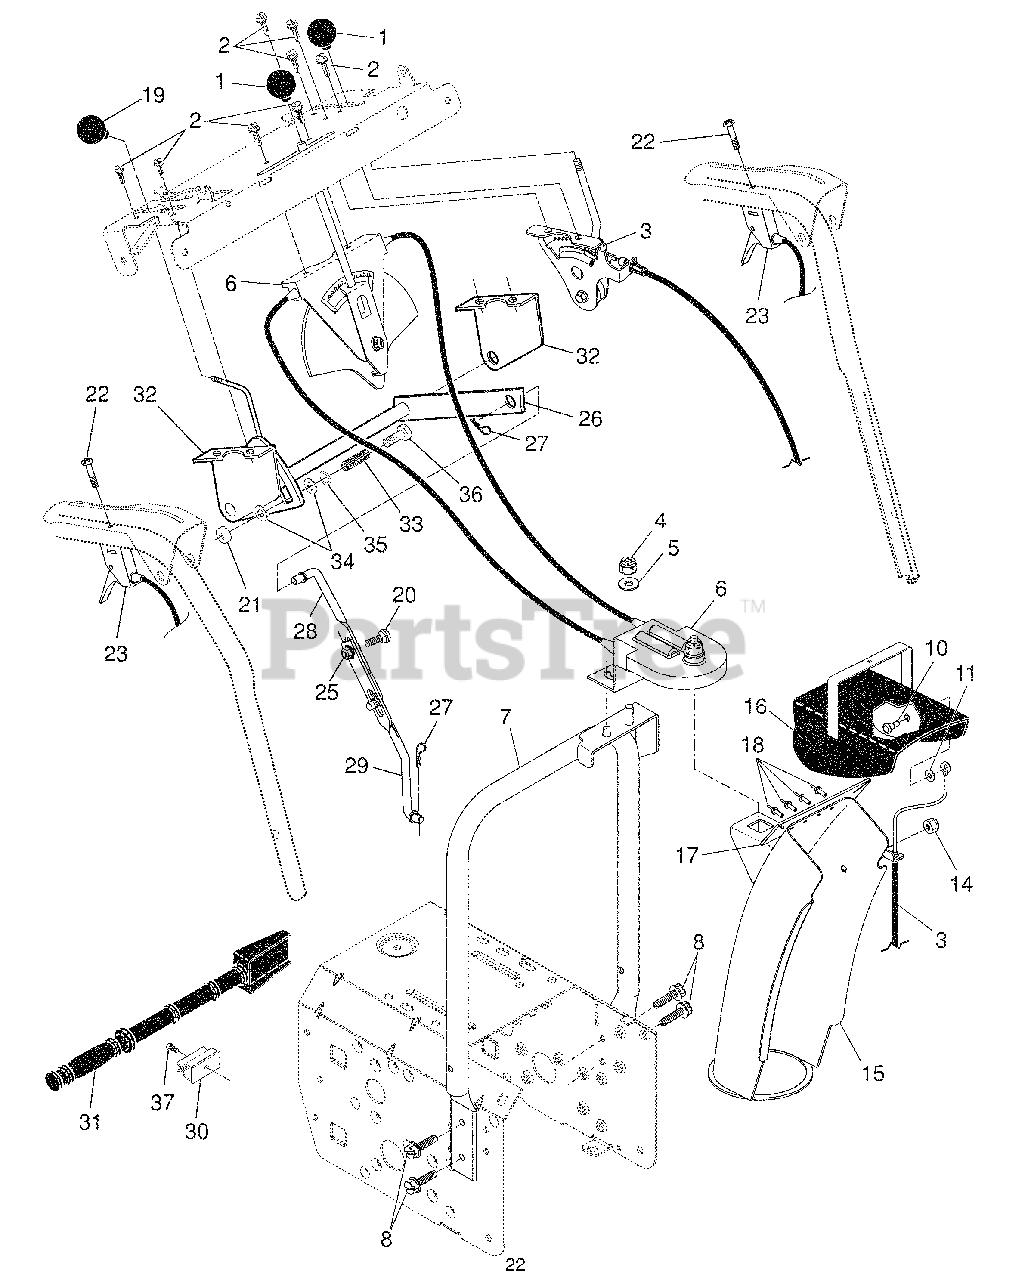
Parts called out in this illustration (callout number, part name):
1	Knob, Lever
2	Screw #10-24 x 5/8
3	Control Assembly, Deflector
4	Nut, Lock 3/8-16
5	Washer, Flat 3/8
6	Control Assembly, Chute Rotater
7	Support, Pivot
8	Screw, Hex Head 5/16-18 x 3/4
10	Bolt, Shoulder
11	Washer, Friction, Nylon
15	Chute Assembly
16	Deflector Assembly
17	Seal, Deflector
18	Rivet, Blind
19	Knob, Speed Control Lever
20	Bolt, Carriage 5/16-18 x 3/4
22	Screw #10-24 x 1-1/2
23	Control Assembly, Power Steering
25	Nut, Lock 5/16-18
26	Lever Assembly, Speed Control
27	Retainer, Hairpin
28	Rod, Upper, Speed Control
29	Rod, Lower, Speed Control
30	Clamp, Clean-Out Tool
31	Tool, Clean-Out
32	Bracket, Shift, Hydro
35	Washer, Friction
